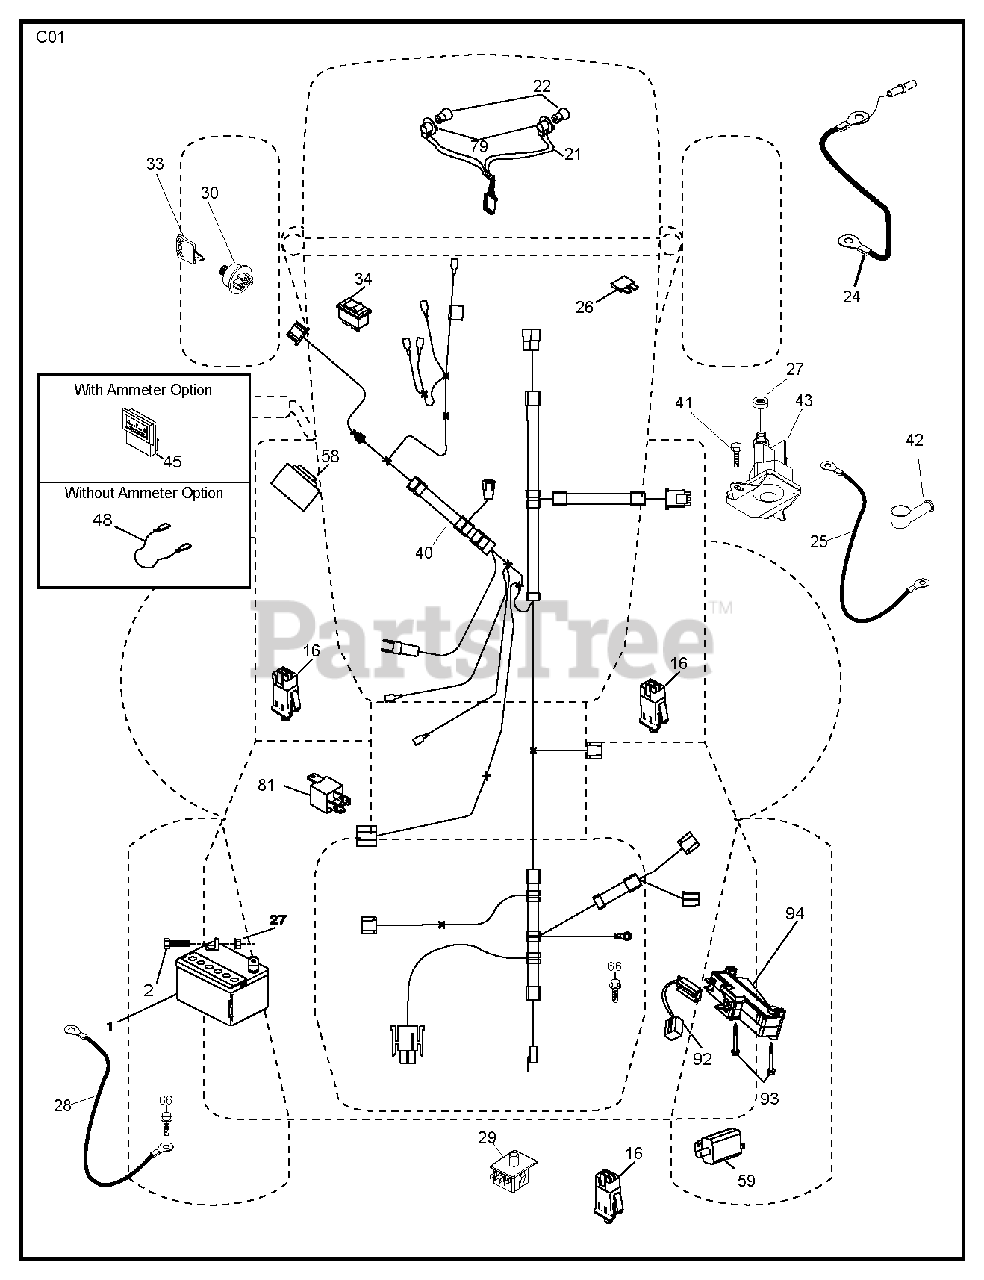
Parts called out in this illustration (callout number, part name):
1	REPL BY 532 12 38-99
16	SWITCH INTERLOOK PUSH-IN
21	HARNESS ASSY LIGHT
22	LIGHTBULB
24	CABLE BATTERY
25	CABLE BATTERY 6 GA. 11" RED
26	FUSE 20AMP
27	NUT
28	CABLE GROUND
29	SWITCH.SEAT.DP W/RAMPS
30	SWITCH.IGN.DELTA.W.LGH.ROS
33	KEY.CHAIN.BLISTER.PACK.GEN.INT
34	SWITCH LT
42	TERMINAL COVER
43	SOLENOID.W/BRASS.PLUNG
58	BUZZER
79	BULB HOLDER ASM.
81	RELAY.ASSY.T
92	HARNESS.PIGTAIL.CONSLE
93	SCREW.PLASTITE
94	MODULE.REVERSE.ROS
